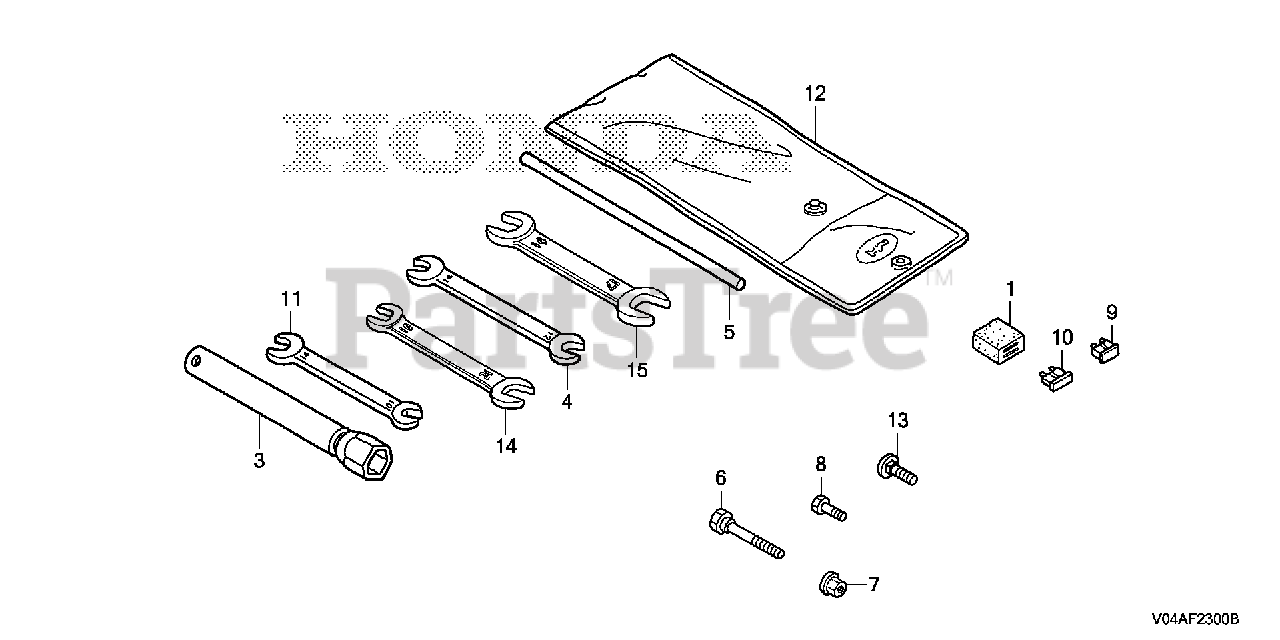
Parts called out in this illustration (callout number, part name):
3	WRENCH, SPARK PLUG (NOT AVAILABLE)
5	HANDLE, BOX WRENCH (NOT AVAILABLE)
7	NUT, SELF-LOCK (6MM)
8	BOLT, SPECIAL (6X18)
9	FUSE, MINI (5A)
12	BAG, TOOL
13	BOLT, CARRIAGE (6X18)
14	WRENCH (10X12) (OPEN END)
15	WRENCH (14X17) (OPEN END)
